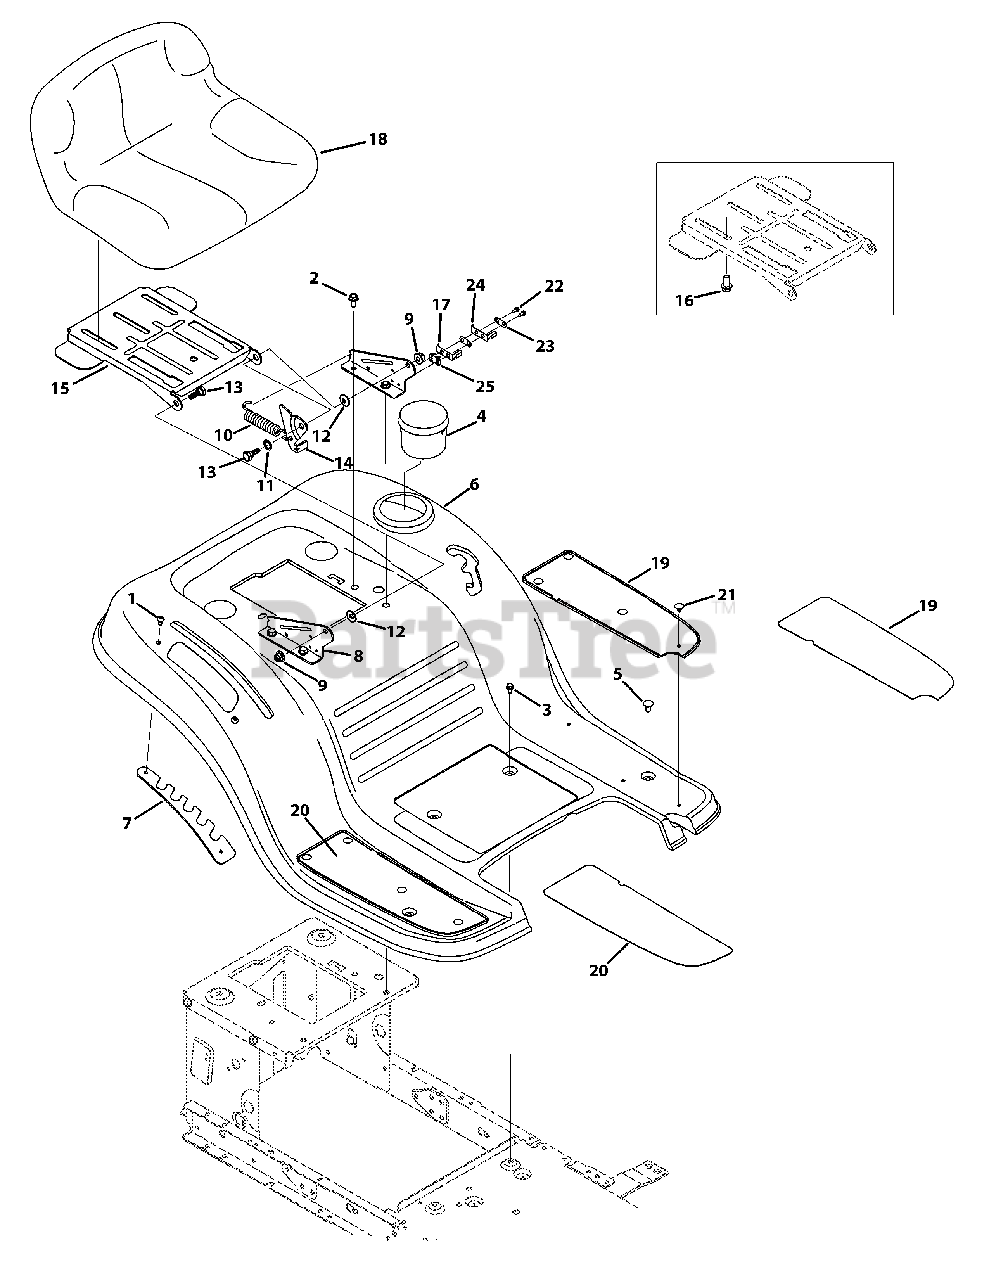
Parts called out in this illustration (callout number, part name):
1	Screw, 1/4-20 x .500
2	Screw, 5/16-18 x .750
3	Screw Pan Torx Head, 1/4-20 x .500
4	Cup Holder
5	Screw Carriage, 1/4-20 x .62
6	Fender
7	Lift Adjuster Bracket
8	Seat Mount Bracket
9	Flangelock Nut, 5/16-18
10	Extension Spring
11	Flat Washer, .510x .750 x .033
12	Bell Washer, .340 x .872 x .060
13	Shoulder Screw, 5/16-18 x .437 x .268
14	Lift Seat Bracket
15	Pivot Seat Manual Adjust Bracket
16	Hex Head Flange, 3/8-16 x .875
17	Inner Seat Spring
18	Med. Back Seat, Black
19	Foot Pad, Abrasive, LH
19	Foot Pad, LH
20	Foot Pad, Abrasive, RH
20	Foot Pad, RH
21	Insulator Boss Plate
22	Screw, 8-18 x .500
23	Insulator Plate
24	Outer Seat Spring
25	Insulator Boss Plate
